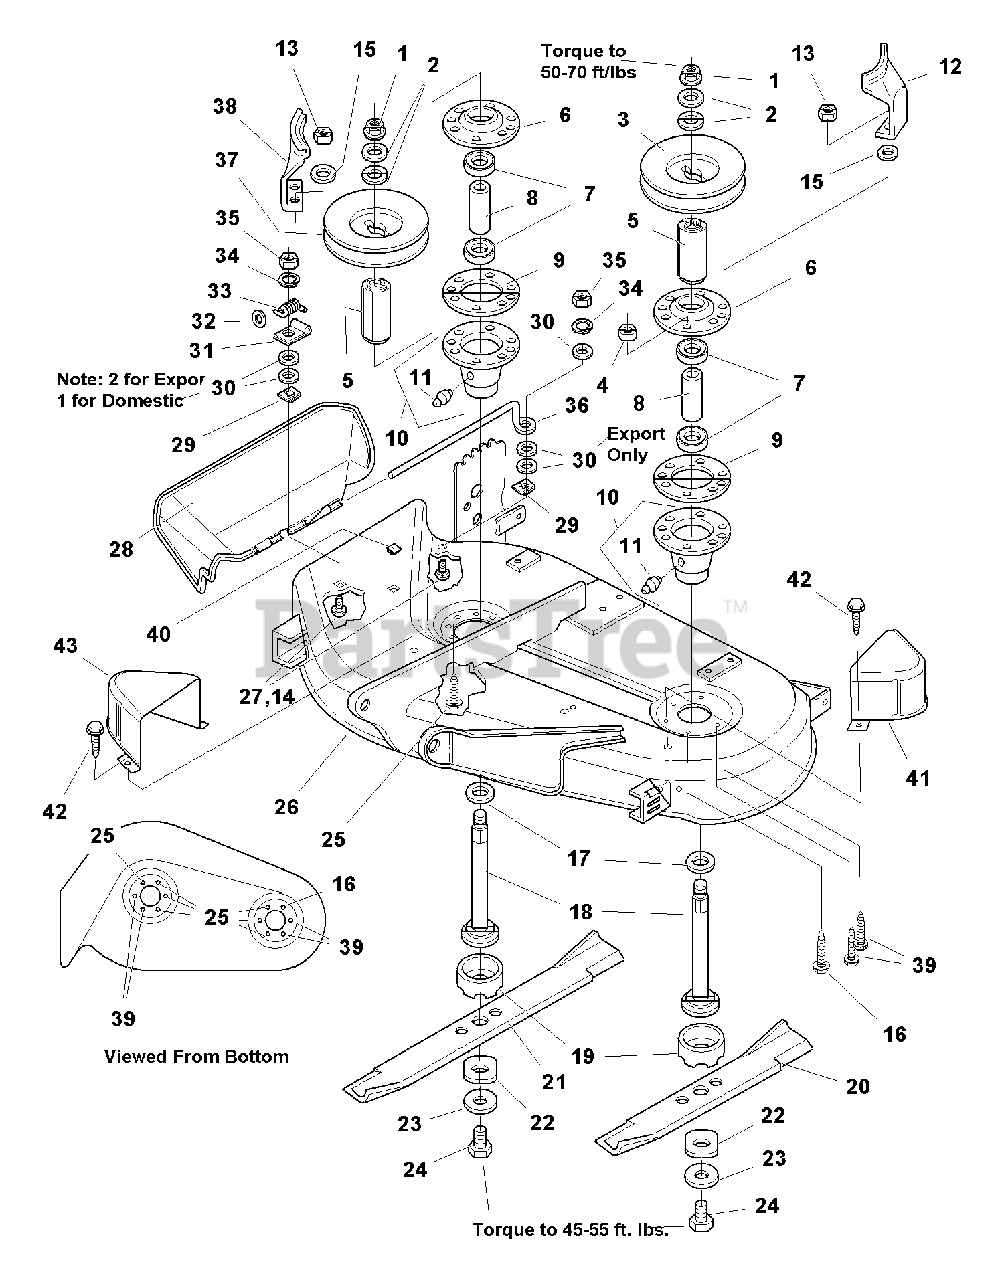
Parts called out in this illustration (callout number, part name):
1	NUT, Hex, Flange, 9/16-8
2	WASHER, Belleville
3	PULLEY, LH, 4" OD
4	NUT, Hex, 5/16-18
6	COVER, Arbor Housing
9	GASKET, Foam
10	HOUSING ASSEMBLY, Arbor Bottom, w/Lube Fitting
11	FITTING, Grease
12	STOP, Belt, LH
13	NUT, Hex, Whiz Lock, 5/16-18
14	CARRIAGE BOLT, 1/4-20 x 1-1/4
15	WASHER, Flat, 3/8
16	CAPSCREW, Taptite Hex Washer Head, 5/16-18 x 1-3/4
18	SHAFT, Arbor
19	SHIELD, Grass, Lower
20	BLADE, Mower, 16-1/8
21	BLADE, Mower, 22-1/4
22	WASHER, Hex
23	WASHER, Spring
24	CAPSCREW, Hex Head, 7/16-14 x -1/4
25	CAPSCREW, Taptite Hex Washer Head, 5/16-18 x 3/4
26	MOWER DECK HOUSING, 38", Orange
26	MOWER DECK HOUSING, 38", Red
26	MOWER DECK HOUSING, 38", Black
27	CARRIAGE BOLT, 1/4-20 x 7/8
27	CARRIAGE BOLT, 1/4-20 x 1-1/4, (6 Total for CE)
28	DEFLECTOR, Plastic
29	NUT, Push On
30	CARRIAGE BOLT, 1/4-20 x 1-1/4
32	WASHER, Plain, 5/16
35	NUT, Hex, 1/4-20 ESNA
36	ROD, Deflector, Front
37	PULLEY, RH, 5-1/4OD
38	STOP, Belt, RH
39	CAPSCREW, Taptite Hex Washer Head, 5/16-18 x 1
40	PLUG, Plastic
41	COVER ASSEMBLY, LH
42	CARRIAGE BOLT, 1/4-20 x 1-1/4
43	COVER ASSEMBLY, RH
